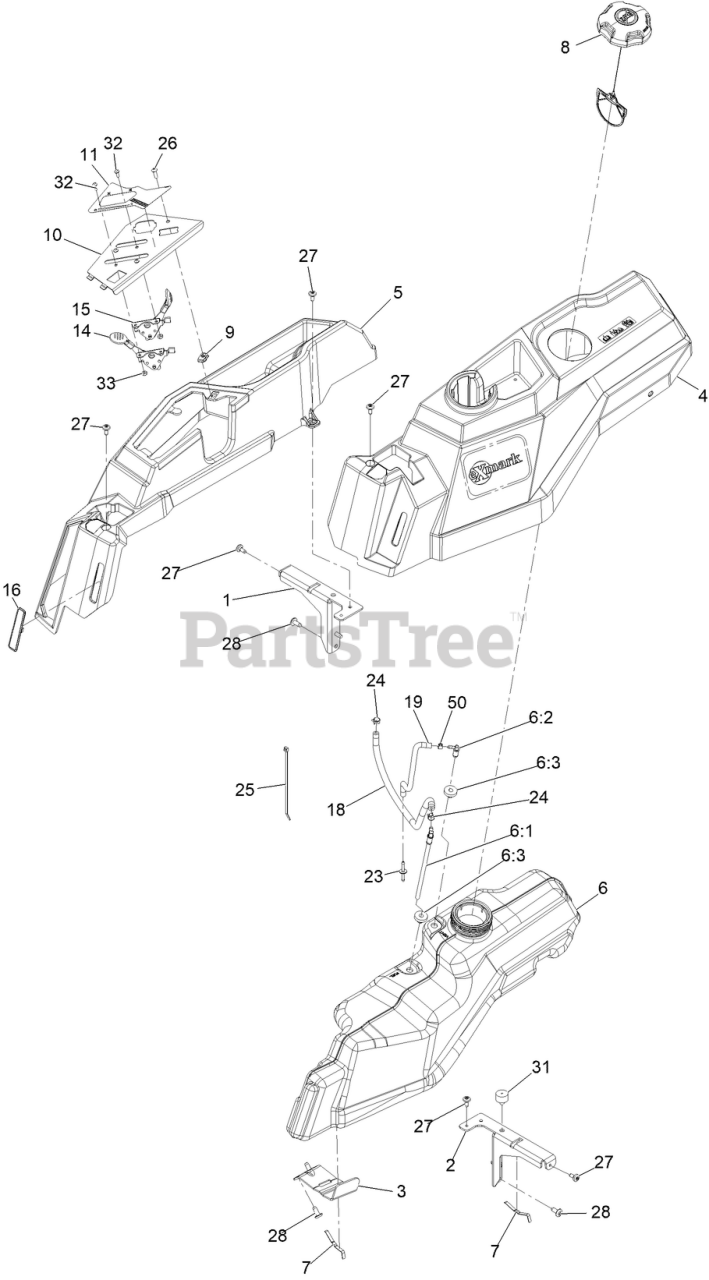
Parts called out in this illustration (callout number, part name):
1	SUPPORT-POD, RH
2	SUPPORT-POD, LH
3	SUPPORT-TANK, FUEL
4	POD- LH
5	POD- RH
6	TANK-FUEL ASM
6:1	Connector-Elbow, 90 DEG
6:2	Fitting-Elbow 90
6:3	BUSHING
7	SPRING
8	CAP-FUEL, RATCHETING
10	PANEL- CONTROL
11	DECAL-CONTROL PANEL
14	CABLE-CONTROL, THROTTLE
15	CABLE-CONTROL, CHOKE
16	PLUG-SC
18	HOSE-FUEL
19	Hose-Fuel
23	Adapter Orifice
24	CLAMP-HOSE
25	TIE-CABLE
26	SCREW-PRH
27	SCREW-SHOULDER
31	BUMPER-GROMMET
32	SCREW-PPH
33	NUT-LOCK, NI
50	CLAMP-HOSE
